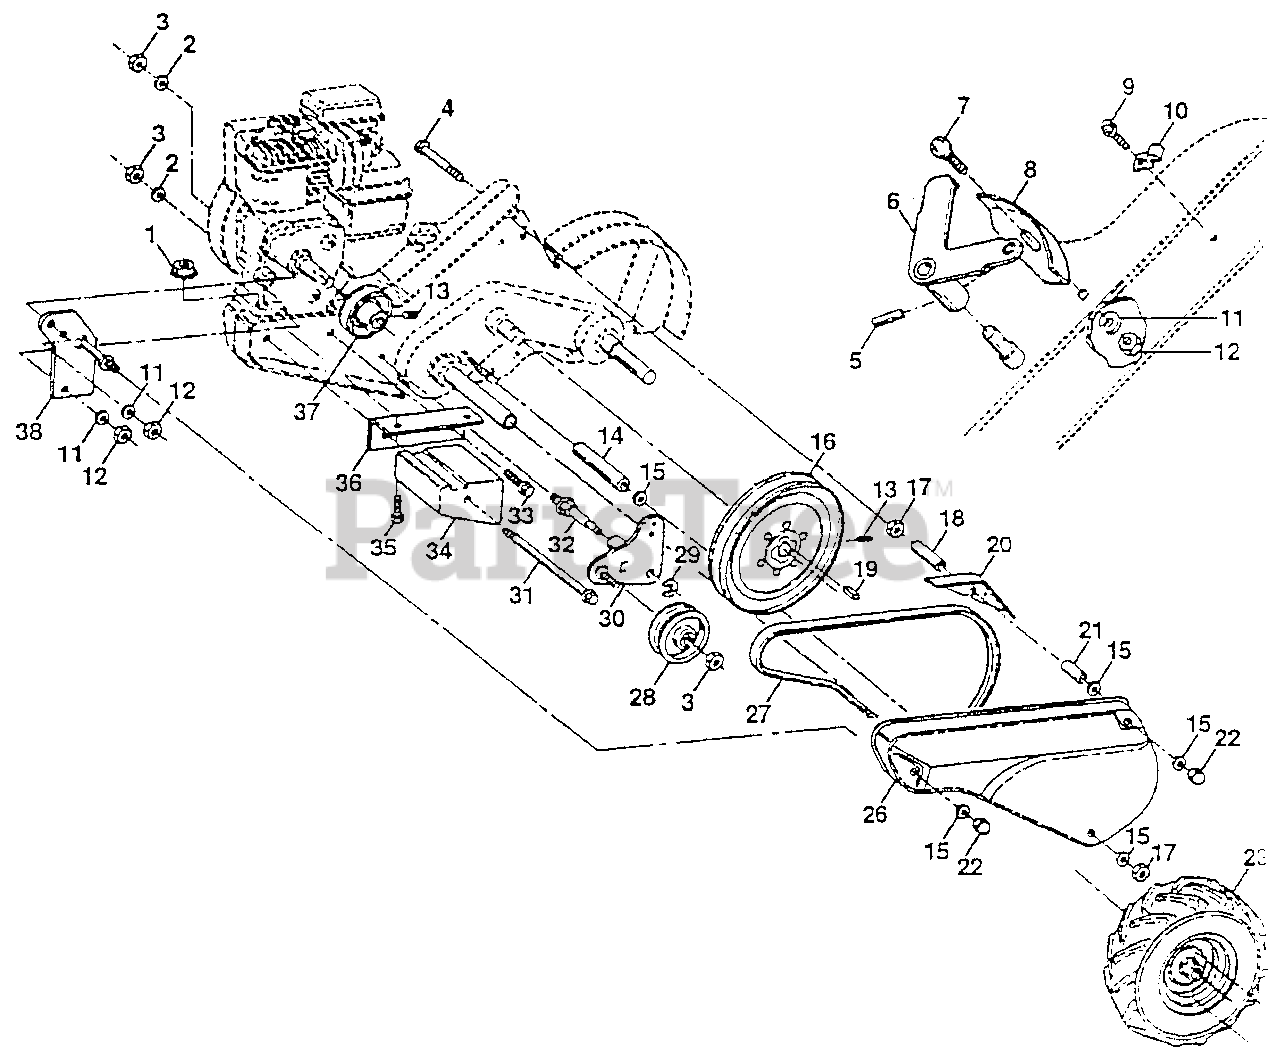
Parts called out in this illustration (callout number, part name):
1	Nut, Keps 5/16-18
2	Washer, Lock 3/8
3	Nut, Hex 3/8-16
4	Bolt, Hex 5/16-18 x 4-1/4
5	Pin, Roll
6	Lever, Shift
7	Bolt, Carriage 1/4-20 x 1/2 Gr. 5
8	Plate, Shift Indicator
9	Screw, Hex, Washer Head, Slotted #10-24 x 1/2
11	Washer, Lock 1/4
12	Nut, Hex 1/4-20
13	Screw, Set, Hex 5/16-18 x 3/8
14	Spacer, Split 0.327 x 0.42 x 2.68
15	Washer 11/32 x 11/16 x 16 Ga.
16	Sheave, Transmission
17	Nut, Hex 5/16-18
18	Spacer, Split 0.327 x 0.42 x 1.75
19	Key, Square 3/16 x 1-1/8
20	Guard, Pinch Point
21	Spacer, Split 0.327 x 0.42 x 1.627
22	Nut, Cap 5/16-18
23	Tire Valve
24	Rivet, Drilled
25	Clip, Hairpin
26	Guard, Belt
28	Pulley, Idler
29	Ring, Klip
30	Bracket, Idler
31	Bolt, Hex 5/16-16 x 12
32	Shaft, Idler Arm
33	Bolt, Hex 3/8-16 x 1
34	Counterweight, L. H.
35	Bolt, Hex 16-18 x 1-1/2
36	Bracket, Reinforcement, L. H.
37	Sheave, Engine
38	Bracket, Guard Belt
